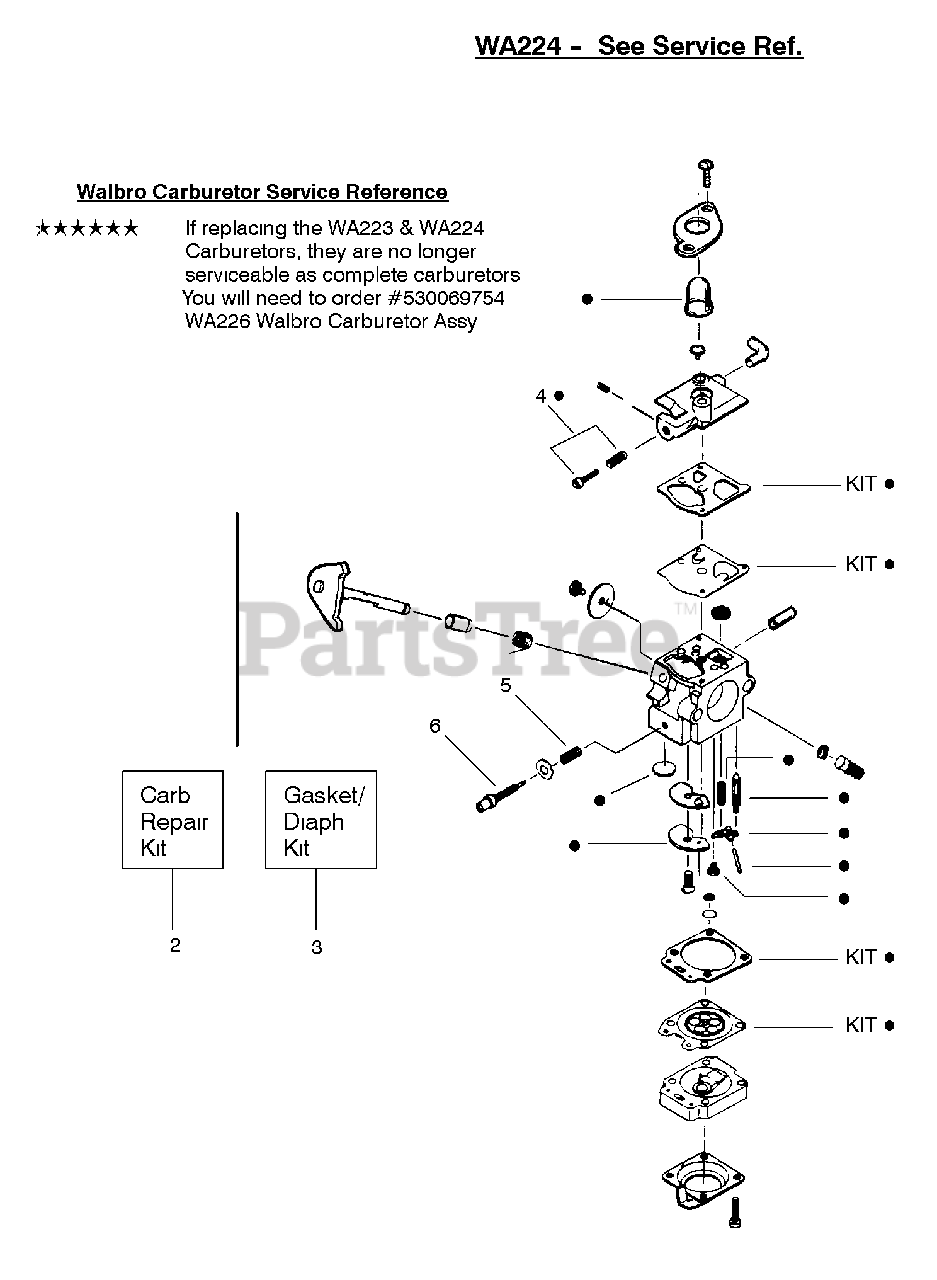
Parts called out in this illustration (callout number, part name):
2	Carburetor Repair Kit WA224
3	Gasket/Diaphragm WA223, WA224 & WA226
4	Idle Screw & Spring Kit
5	Low Speed Spring
6	Low Speed Needle
